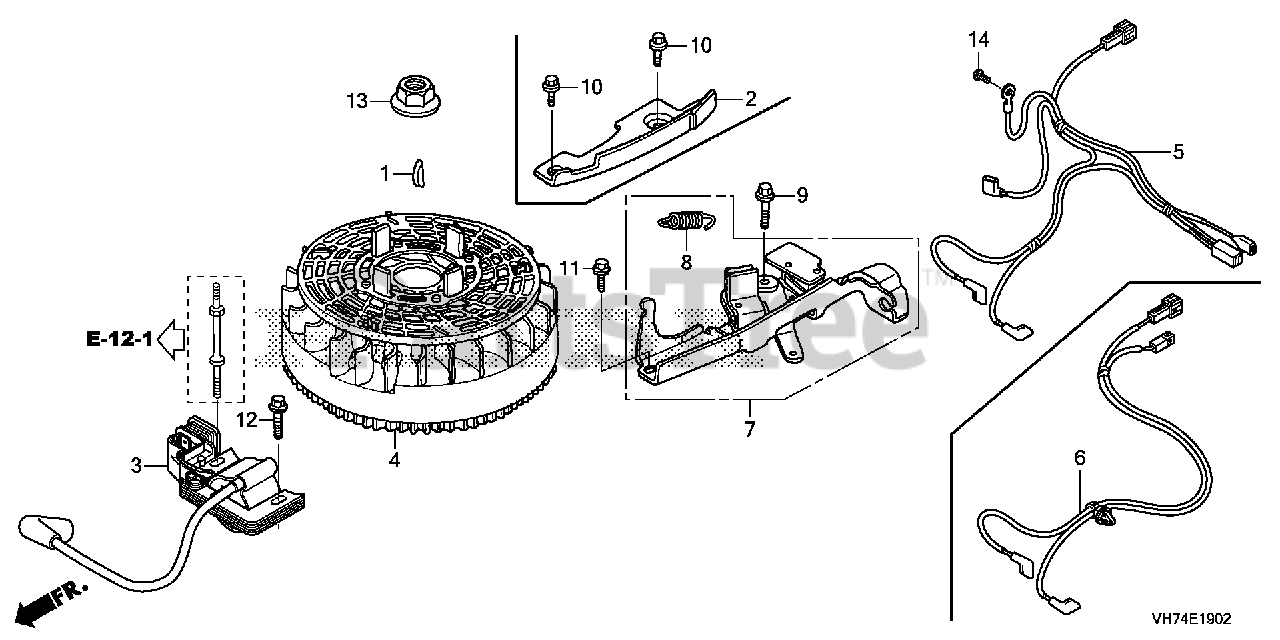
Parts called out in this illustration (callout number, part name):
1	KEY, SPECIAL WOODRUFF (25X18)
3	COIL ASSY., IGNITION
4	FLYWHEEL ASSY. (PHELON) (USE FOR IGN. COIL OF PHELON) (NA USE ALT:31105-Z0Y-922)
5	WIRE, COMBINATION
7	BRAKE SUB-ASSY.
8	SPRING, BRAKE LEVER
9	BOLT, FLANGE (6X23) (CT200)
11	BOLT, FLANGE (6X14) (CT200)
12	BOLT, FLANGE (6X23) (CT200)
13	NUT, FLANGE (14MM)
14	SCREW, PAN (5X8)
